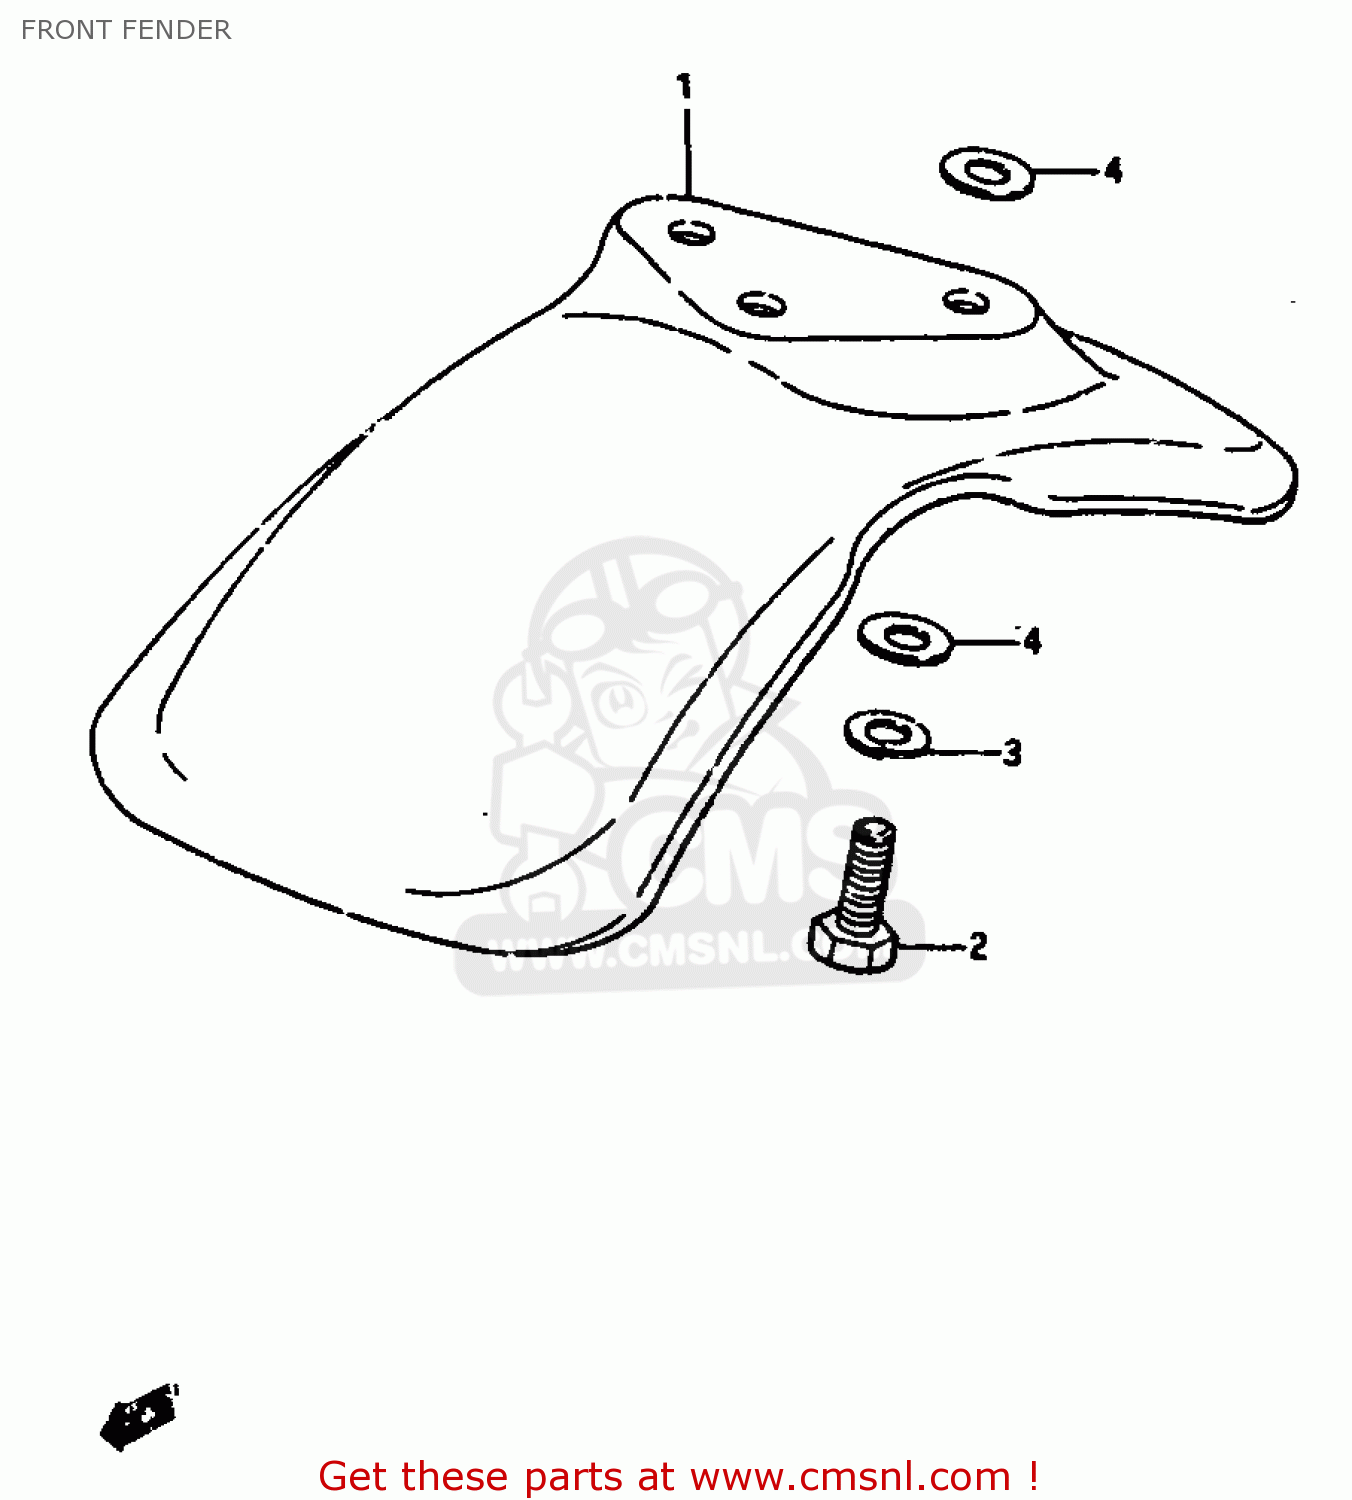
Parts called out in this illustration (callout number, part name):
1	FENDER,FR
2	BOLT
3	WASHER,LOCK
4	WASHER(6.5X18X1)
